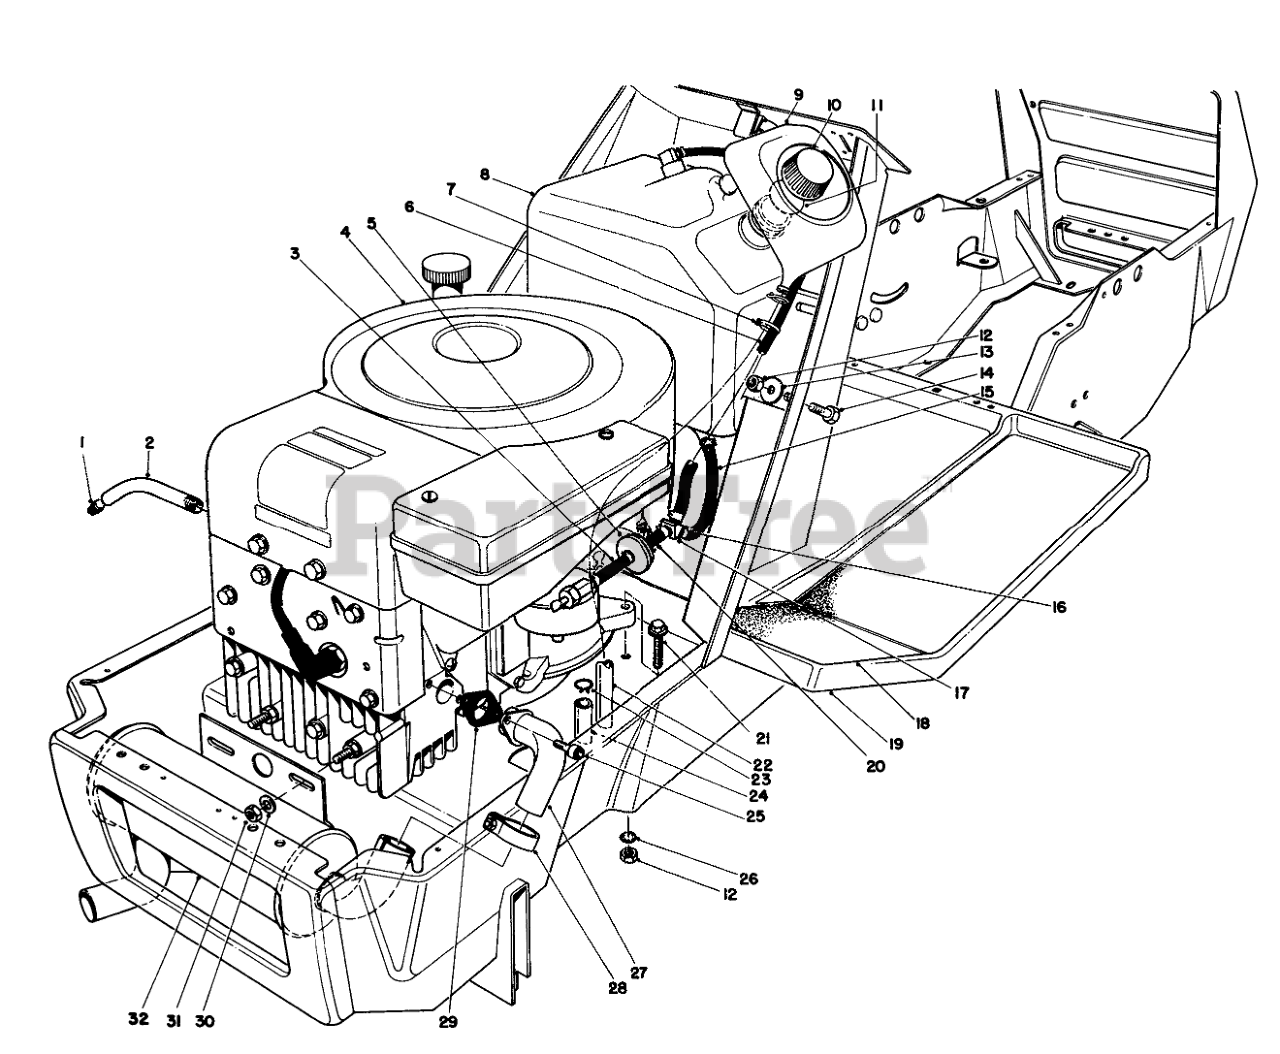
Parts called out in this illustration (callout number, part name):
1	PLUG-PIPE, SQH
2	OIL DRAIN TUBE
3	Hose Gas
4	Engine
5	Filter-Fuel
6	HOSE -RETURN
7	216 Washer
8	Gas Tank Assy. (Incl. Ref. #9)
9	Funnel-Overflow
10	Gas Cap Assy. (Incl. Ref. #11)
11	GAS CAP GASKET
12	NUT-LOCK, NI
13	WASHER
14	Screw
15	HOSE-FUEL
16	FUEL HOSE CLAMP
17	Fitting-Barbed Y
18	LH FOOT TREAD
19	Frame
20	GAS HOSE
21	SCREW-HH
22	FUNNEL HOSE
23	HOSE CLAMP
24	Hose-Carburetor Drain
25	SCREW-HSH
26	WASHER-LOCK, INTERNAL
27	10 HP EXHAUST PIPE WA
28	MUFFLER CLAMP
29	Exhaust Gasket
30	WASHER-PLAIN
31	NUT-LOCK, CONE
32	EXHAUST MUFFLER 10 HP
